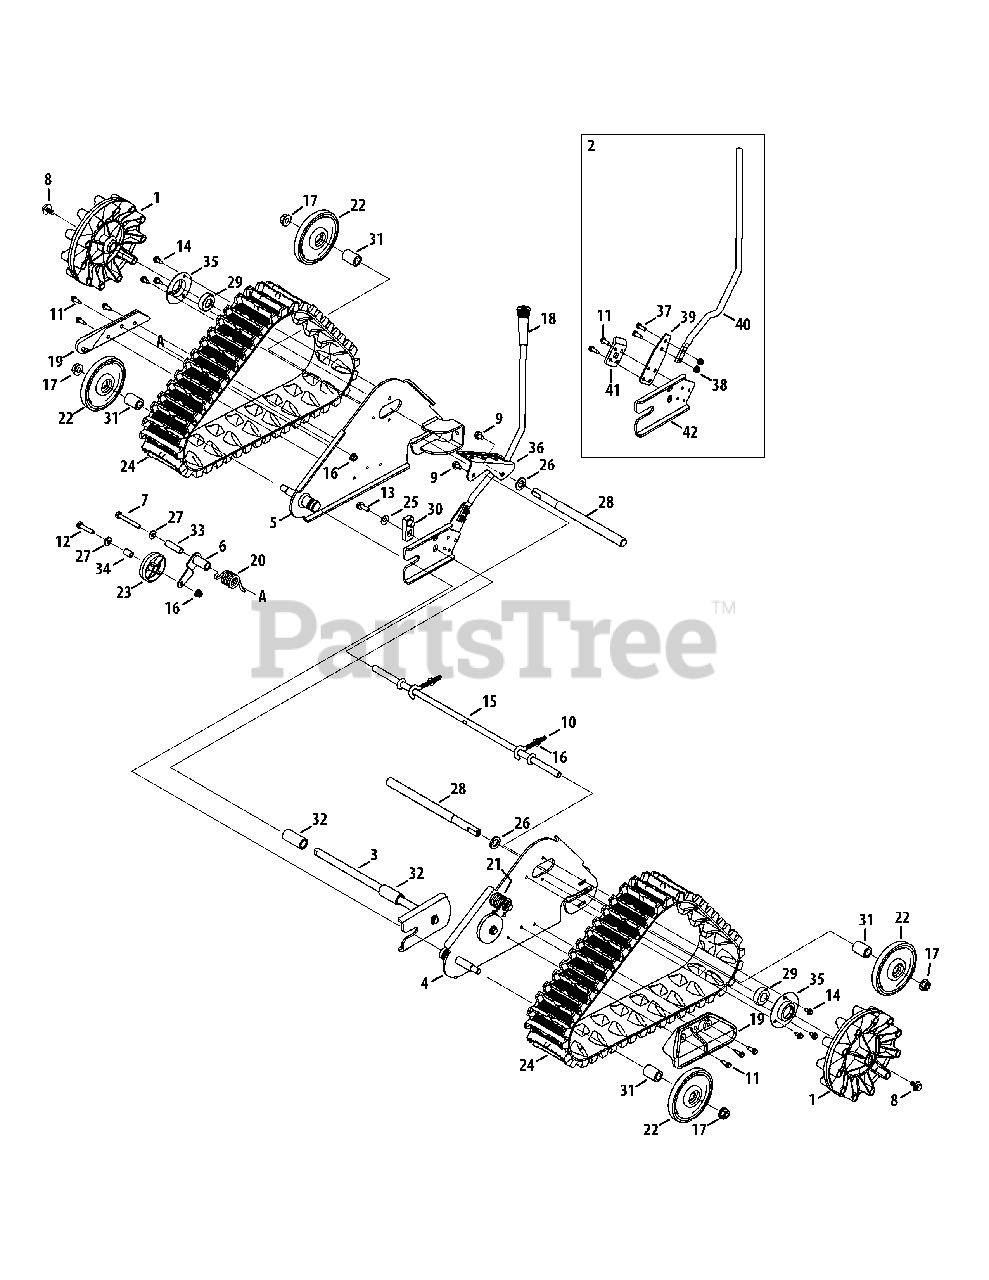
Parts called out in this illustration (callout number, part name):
1	Track Drive Wheel
2	Height Adjustment Lever Ass'y
3	Pivot Bracket Assembly
4	Track Mount Plate Assembly, LH
5	Track Mount Plate Assembly, RH
6	Pivot Tension Bracket Assembly
7	Hex Screw, 5/16-18, 2.50, Gr5
8	Screw, 5/16-24 x .750
9	Hex Washer Screw, 5/16-18 x .875
10	Eye Bolt, 5/8 x 2.375, 5/16-18
11	Hex Washer Screw, 1/4-20 x .625
12	Hex Cap Screw, 5/16-18 x 1.50
13	Hex Washer Screw, 5/16-18 x .875
14	Hex Washer Screw, 1/4-20 x .625
15	Rear Wheel Axle
16	Nut, Flange lock, 5/16-18
17	Flange Lock Nut, 1/2-13
18	Grip, .5 ID x 3.45
19	Track Skid
20	Torsion Spring
21	Torsion Spring
22	Wheel, 5.00 OD
23	Track Tension Wheel
24	Track, 61mm x 22 Pitches
25	Washer, Bell, .340 x .872
26	Flat Washer, .672 x 1.125 x .125
27	Flat Washer, .344 x .750 x .120
28	Axle, .75 OD x 11.06 LG
29	Ball Bearing, 17 x 40 x 12
30	Height Adjustment Adapter
31	Spacer, .63 x 1.00 x 1.42
32	Spacer, .632 x 1.00 x 1.42
33	Sleeve, .33 x .50 x 1.73
34	Sleeve, .33 x .50 x .75
35	Cup Bearing
36	Height Adjustment Index Bracket
37	Hex Cap Screw, 1/4-20 x .75
38	Nut, Flangelock, 1/4-20
39	Lever Mounting Bracket
40	Height Adjustment Lever
41	Lever Pivot Bracket
42	Height Adjustment Pivot Bracket
